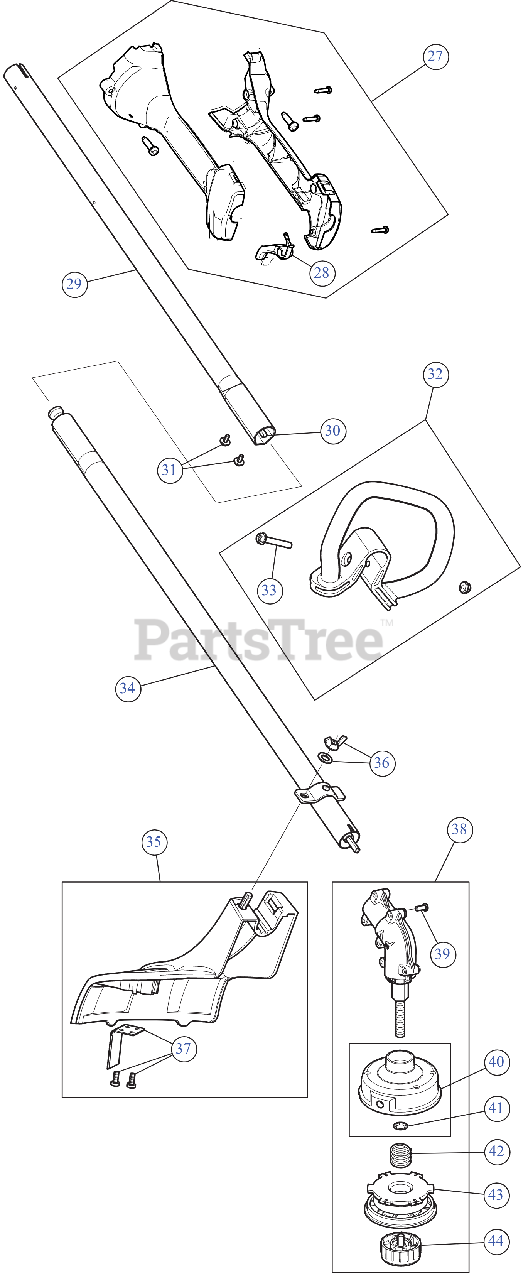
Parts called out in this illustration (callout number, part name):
27	THROTTLE GRIP ASSEMBLY
28	THROTTLE TRIGGER
29	UPPER BOOM ASSEMBLY
30	UPPER SHFT
31	SCREW 8-32X3/8
32	D-HANDLE
33	BOLT 1/4-20X1 1/2
34	LOWER BOOM ASSEMBLY
35	GUARD & BLADE ASSEMBLY
36	BLADE GUARD MOUNTING HARDWARE
37	BLADE ASSEMBLY W/HDW
38	GEARBOX ASSEMBLY
39	SCREW 8-32X.437
40	REEL:OTR W/RET
41	RETAINER .625 OD 2
42	SPRING-SPOOL
43	REEL-INNER SPOOL
44	BUMP HEAD KNOB ASSEMBLY
